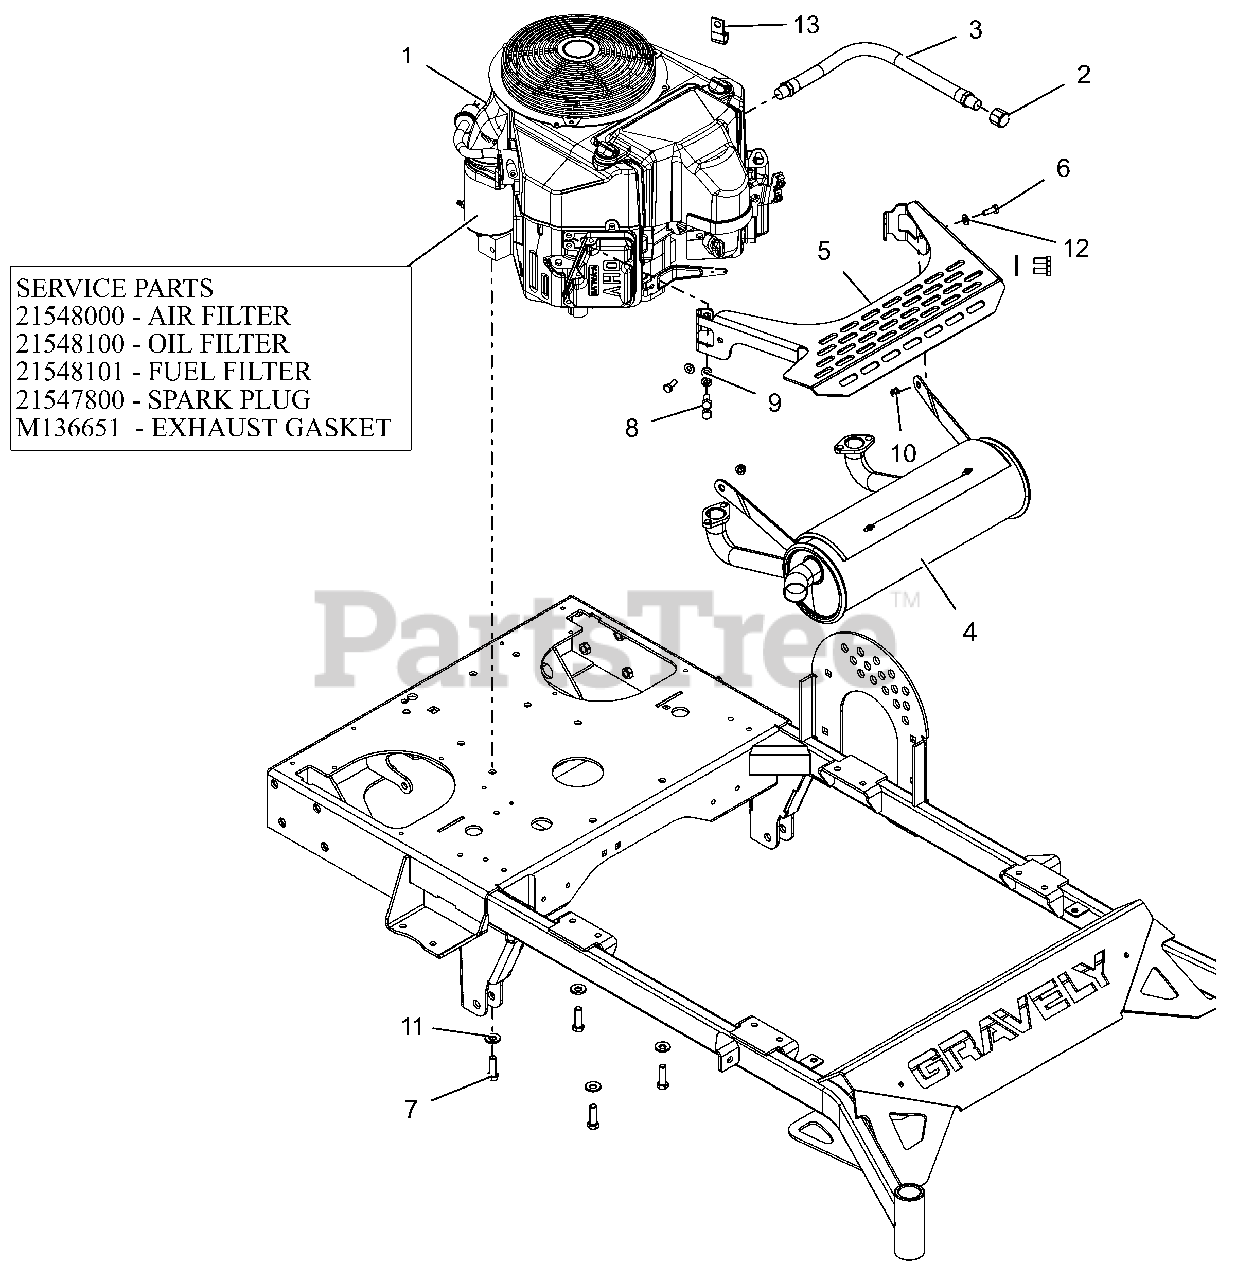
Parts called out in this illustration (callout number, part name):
1	ENG. KAW FS600
1	AIR FILTER, KAWASAKI FR
1	OIL FILTER, KAWASAKI FR
1	FUEL FILTER-KAWASAKI FR
1	SPARK PLUG, KAWASAKI FR
1	GASKET, MUFFLER #
2	PIPE CAP 3/8 NPT FEMALE
3	DRAIN, M20 OIL
4	MUFFLER, KAW FS PROWALK
5	KIT, MUFFLER SHIELD W DECALS
6	@BLT-HEX .25-20X.75 GR5 YWZC
7	BLT-HEX.38-16X1.25 G5YZ NYTORQ
8	@BLT-HEX M8-1.25X20 YWZC
9	@WSHR-LK .31X.078 REG YWZC
10	@NUT-LK-NYL-FLG .25-20 YWZC
11	WASHER, 3/8" SPRING DISC
12	@WSHR-FL-STL.281X.62X.065 YWZC
